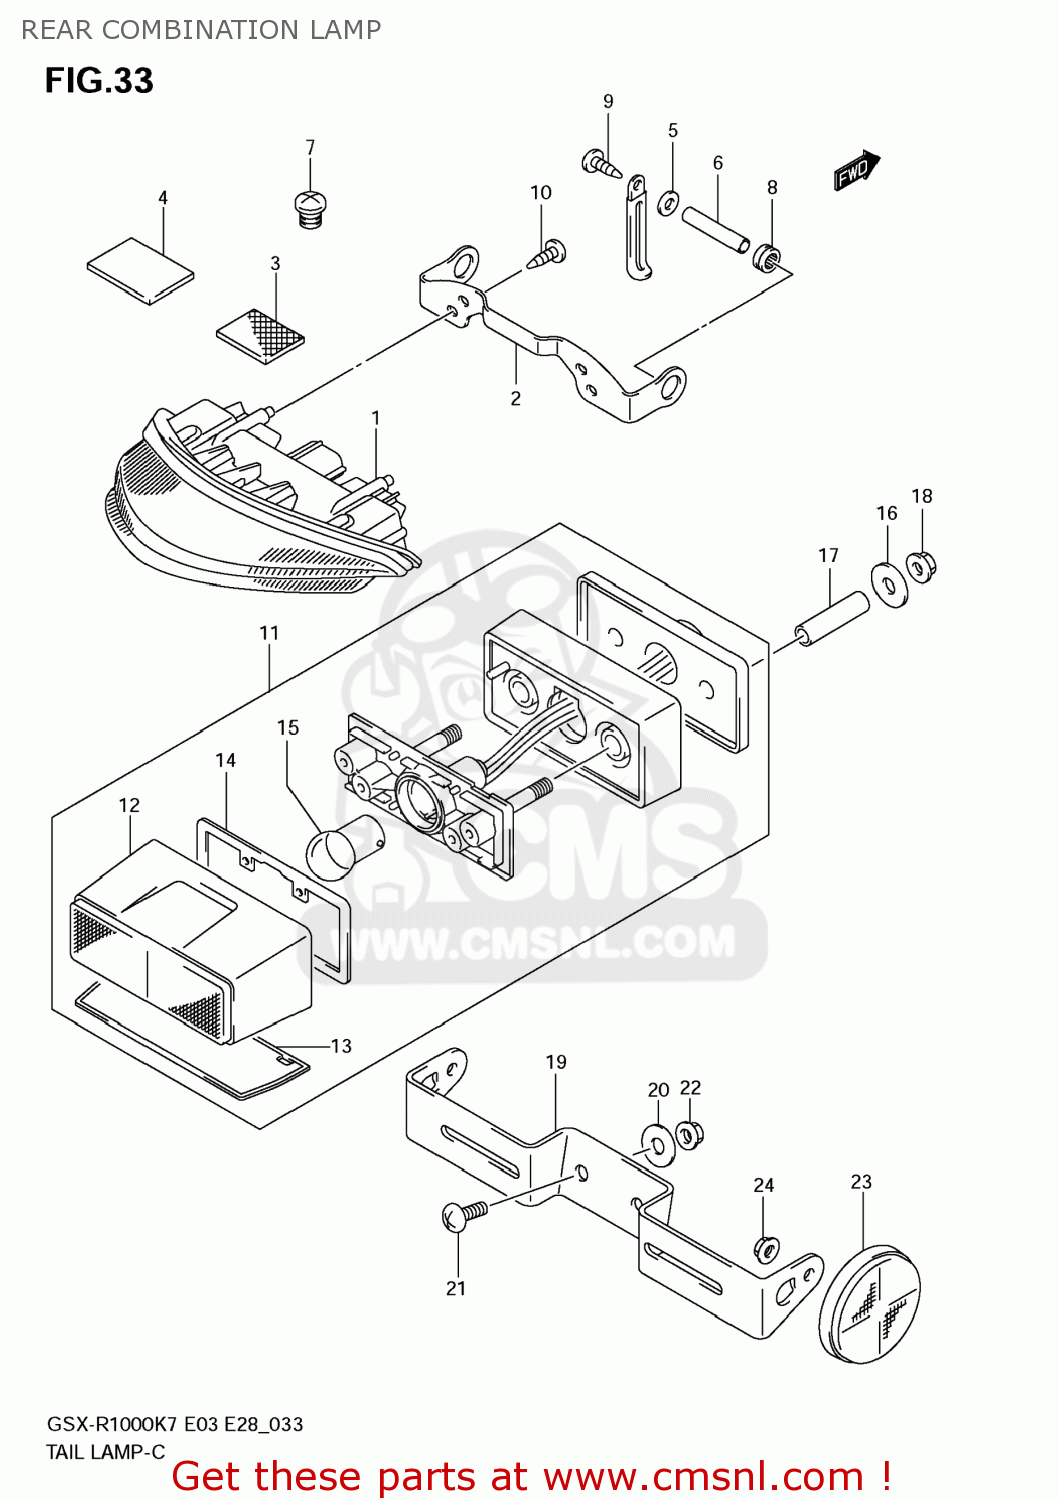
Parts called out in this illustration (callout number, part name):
1	LAMP ASSY,RR COMBINATION
2	BRACKET,RR COMBINATION LAMP
3	FASTENER
4	CUSHION,RR COMBINATION
5	WASHER(5.5X20X1.2)
6	SPACER (5.5X9.5
7	CAP(OD:14)
8	CUSHION
9	SCREW
10	SCREW
11	LAMP ASSY,LICE
12	COVER,LICENSE LAMP
13	LENS LICENCE
14	GASKET (NAS)
15	BULB(12V5W,BF150-40160A)
16	WASHER(6.5X20X1.2)
17	SPACER(6.5X9X33.3)
18	NUT
19	BRACKET,LICENSE PLATE
20	WASHER(6.5X20X1.2)
21	SCREW
22	NUT
23	REFLECTOR ASSY,RR SIDE
24	NUT
